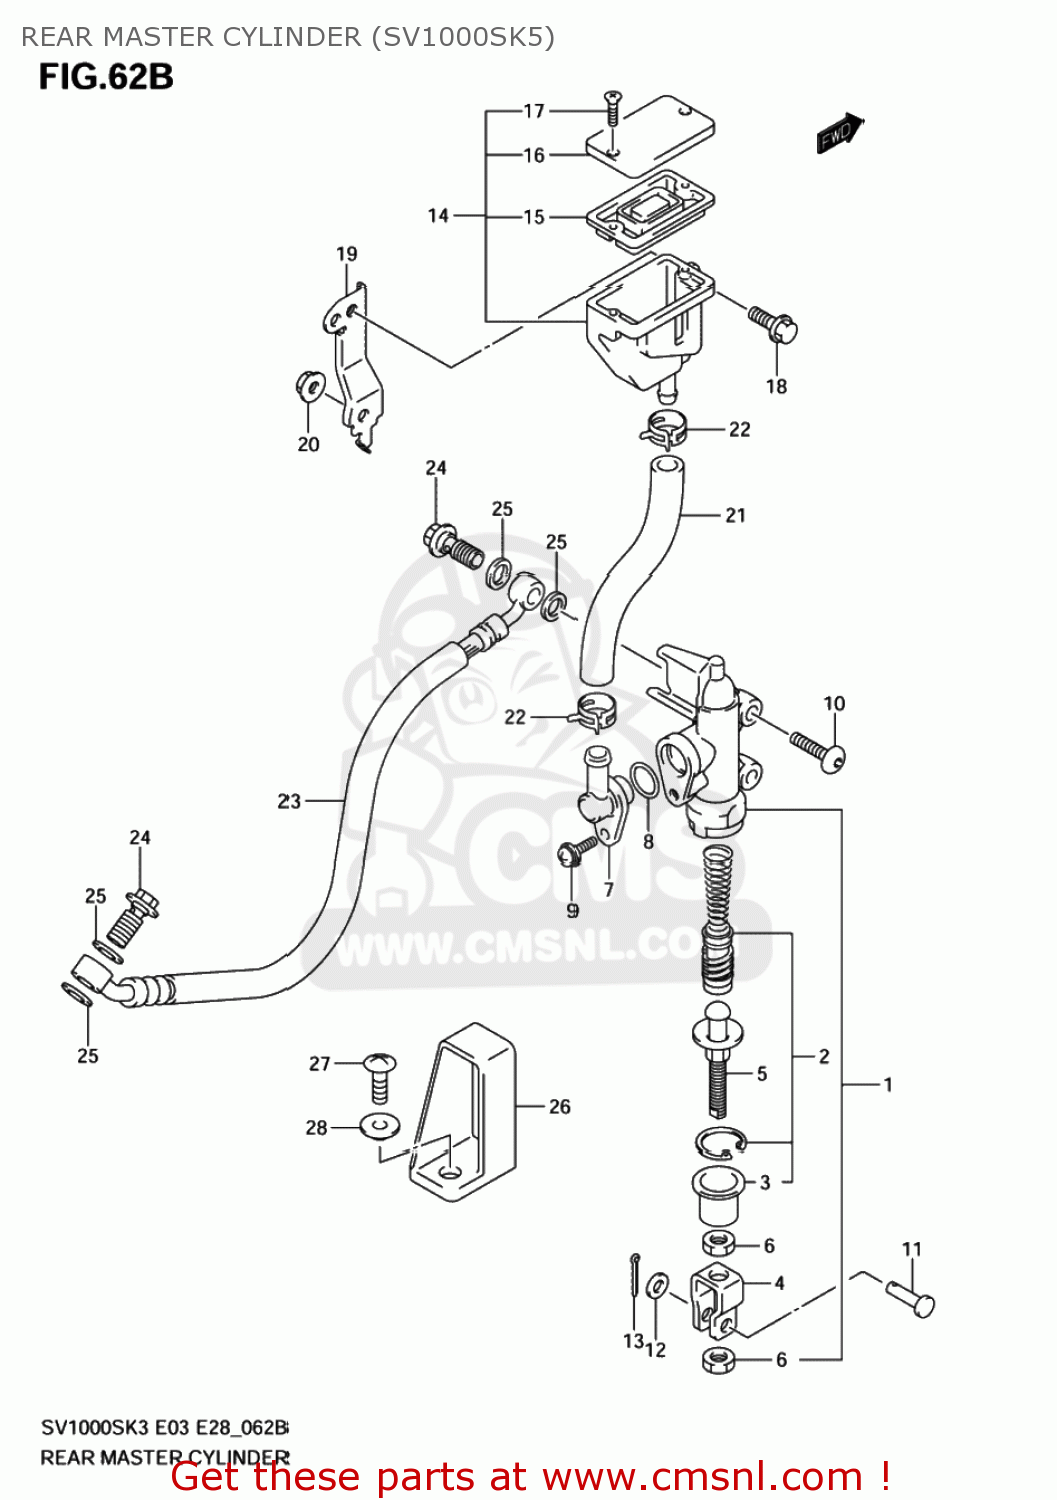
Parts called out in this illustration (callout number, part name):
1	CYLINDER ASSY,RR MASTER
2	PISTON/CUP SET
3	BOOT
4	YOKE
5	ROD,PUSH
6	NUT
7	CONNECTOR
8	O RING
9	SCREW
10	SCREW(6X20)
11	PIN
12	WASHER
13	PIN
14	TANK ASSY,RR RESERVOIR
15	DIAPHRAGM
16	CAP
17	SCREW
18	BOLT(6X12)
19	BRACKET,RR RESERVOIR TANK
20	BOLT
21	HOSE,RR RESERVOIR TANK
22	CLIP
23	HOSE,RR BRAKE
24	BOLT UNION
25	WASHER(10X15X1.5)
26	GUIDE,RR BRAKE HOSE
27	SCREW
28	WASHER
